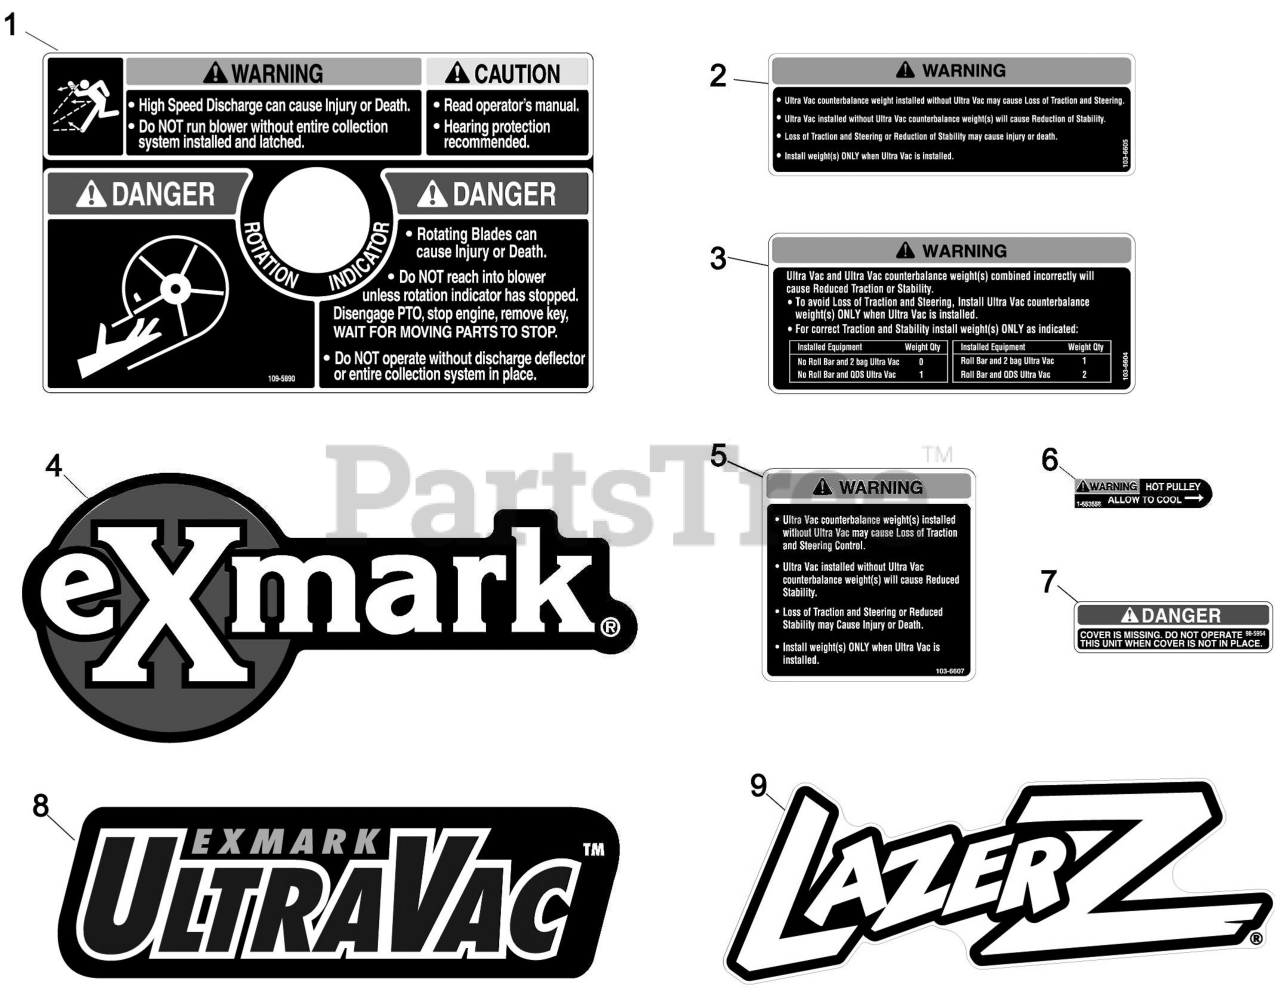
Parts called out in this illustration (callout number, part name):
1	DECAL-WARNING, BLOWER
2	DECAL-WARNING
3	DECAL,WEIGHT
4	DECAL,WEIGHT
5	DECAL,WEIGHT
6	DECAL-WARNING
7	DECAL-COVER, MISSING
8	DECAL-CAUTION
9	DECAL, EXMARK LOGO
10	DECAL, ULTRA VAC
